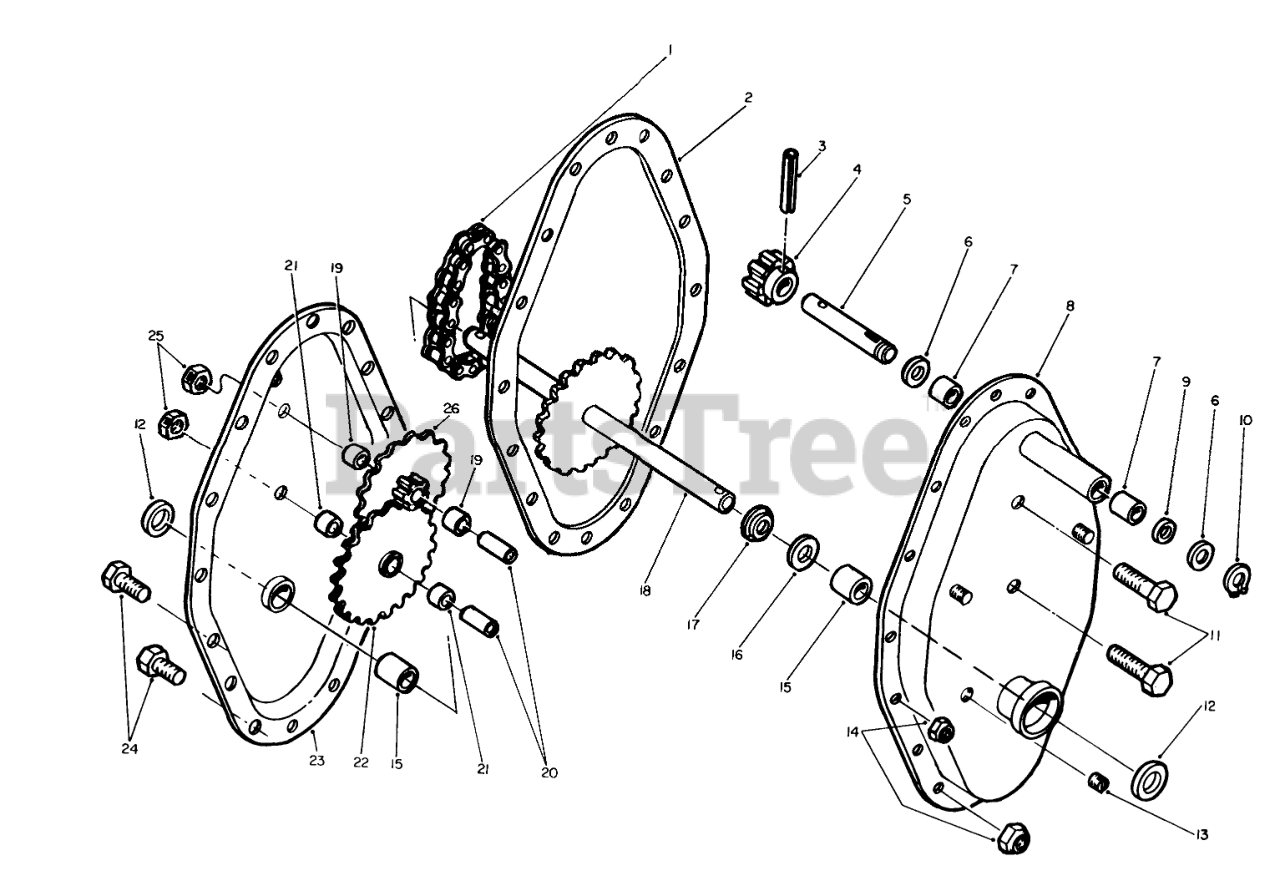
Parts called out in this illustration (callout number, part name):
1	Chain
2	Gasket
3	PIN-SPRING
4	Input Gear
5	Input Shaft
6	Washer
7	Bearing-Input Shaft
8	Chain Case w/Bearings-L.H.
9	Seal-Input Shaft
10	RING-SNAP, EXTERNAL
11	Hex Hd. Capscrew
12	Seal
14	NUT-LOCK, CONE
15	Bearing
16	Shim-Gear
17	Spacer Cup
18	Axle Shaft
19	Bearing
20	Idler Sleeve
21	Bearing
22	Sprocket (Incl. Ref. #21)
23	Chain Case w/Bearings-R.H.
24	SCREW-HH
25	Jam Nut
26	Gear (Incl. Ref. #19)
